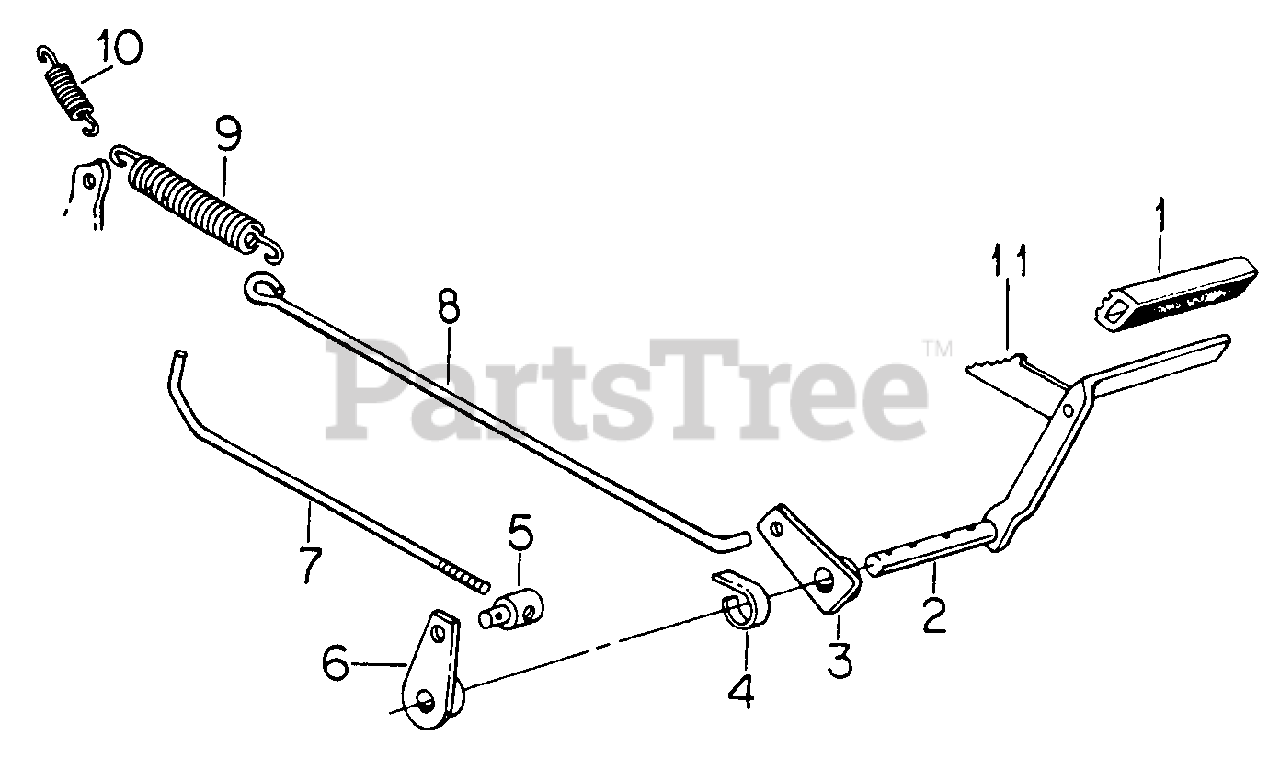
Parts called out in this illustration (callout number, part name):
1	Pad, Pedal
2	Pedal Assy, Clutch & Brake
3	Lever Assy, Foot Pedal Brake
4	Spring, Neutral Start
5	Pin, Adjustment
6	Arm, Pivot
7	Rod, Clutch
8	Rod, Brake
9	Spring, Brake Tension
10	Spring, 1/2 x .251 Extension
11	Ratchet, Brake Lock
